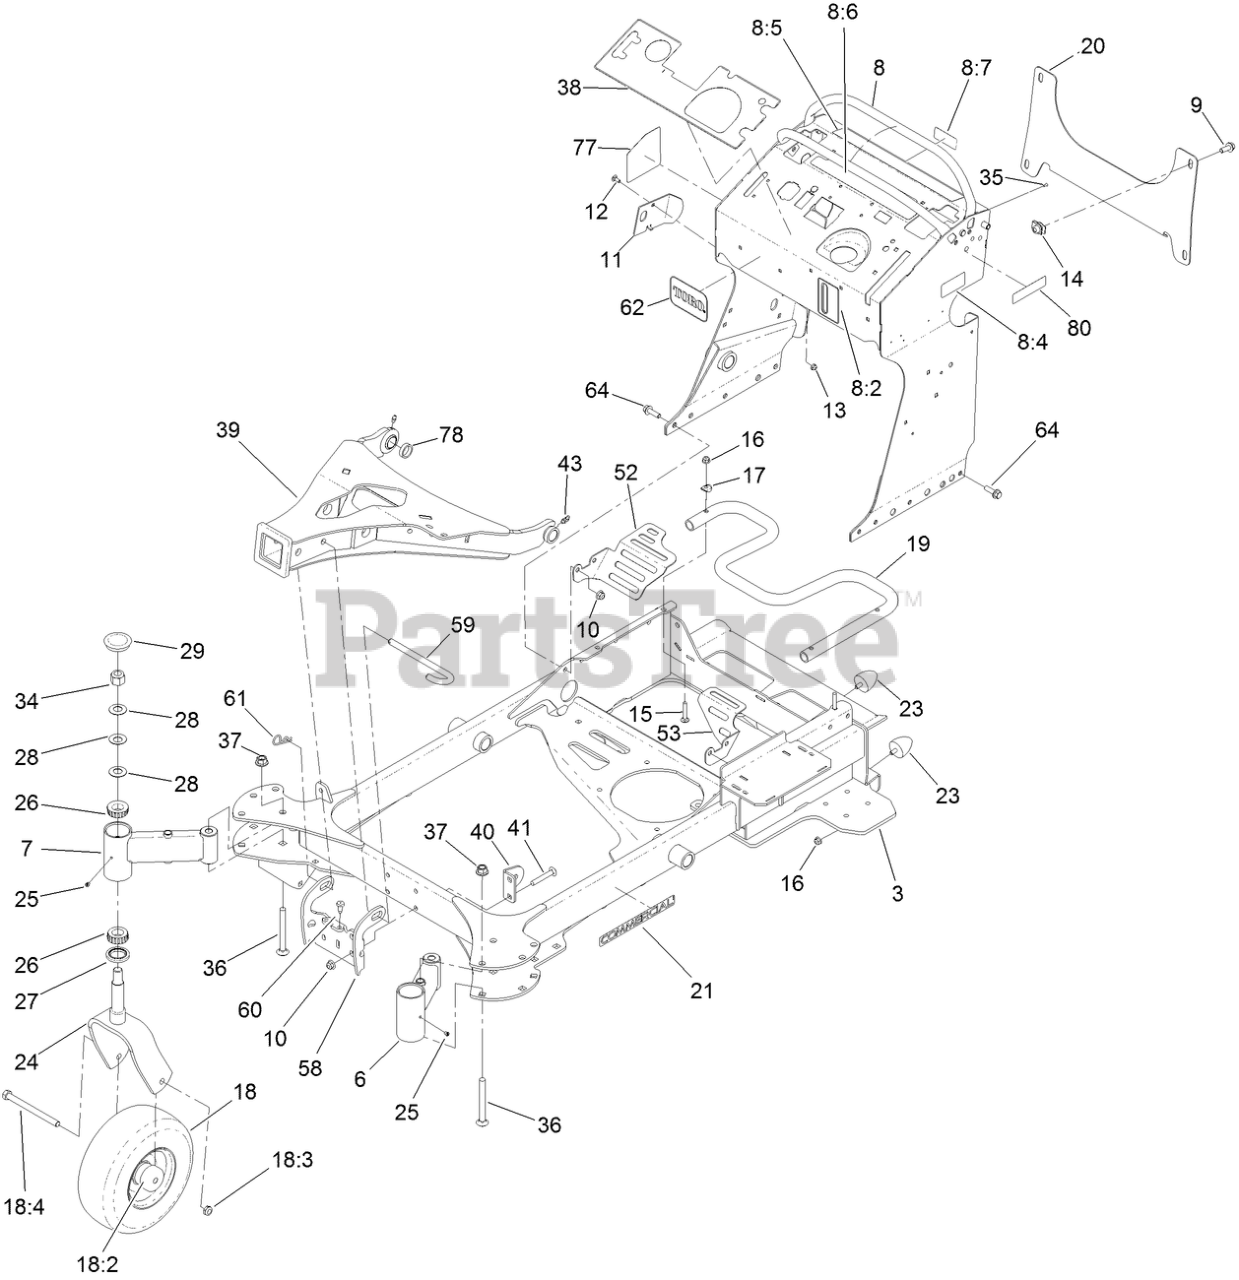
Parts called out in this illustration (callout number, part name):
6	TUBE CASTOR SHORT
7	TUBE CASTOR LONG
8	TOWER DECAL ASM
8:2	DECAL-LEVEL, OIL
8:4	DECAL-FILL, FUEL
8:5	DECAL-WARNING
8:6	DECAL-CONTROLS
8:7	DECAL-FUSE
9	SCREW-HHF
10	NUT-HF, NI
11	PLATE-STRIKER
12	SCREW-CARR
13	NUT-HF
14	NUT-TINNERMAN
15	BOLT-CAR
16	NUT-HF, NI
17	WASHER
18	WHEEL, TIRE AND BEARING ASM
18:2	GUARD-SEAL
18:3	NUT-HEX
18:4	SCREW-HH
19	TUBE-MOUNT, FUEL TANK
20	BRACKET-CROSS
21	DECAL-COMMERCIAL
23	BUMPER-RUBBER
24	FORK-CASTER
26	BEARING-ROLLER, TAPERED
27	SEAL-GREASE
28	WASHER-BELLVILLE
29	CAP-GREASE
34	NUT-LOCK, NI
35	RIVET-POP
36	SCREW-CARR
37	NUT-LOCK
38	DECAL, MULTI-FORCE
40	BRACKET-CYLINDER
41	SCREW-CARR
43	FITTING-GREASE, 90 DEG
52	GUARD-FAN, RH
53	GUARD-FAN, LH
58	BRACKET-LOCK
59	PIN-HITCH
60	BUMPER-RUBBER
61	PIN-HAIR
62	DECAL-LOGO, TORO
64	SCREW-HHF
77	DECAL SERVICE-MULTIFORCE
78	SPACER
80	DECAL-ARRESTOR, SPARK
